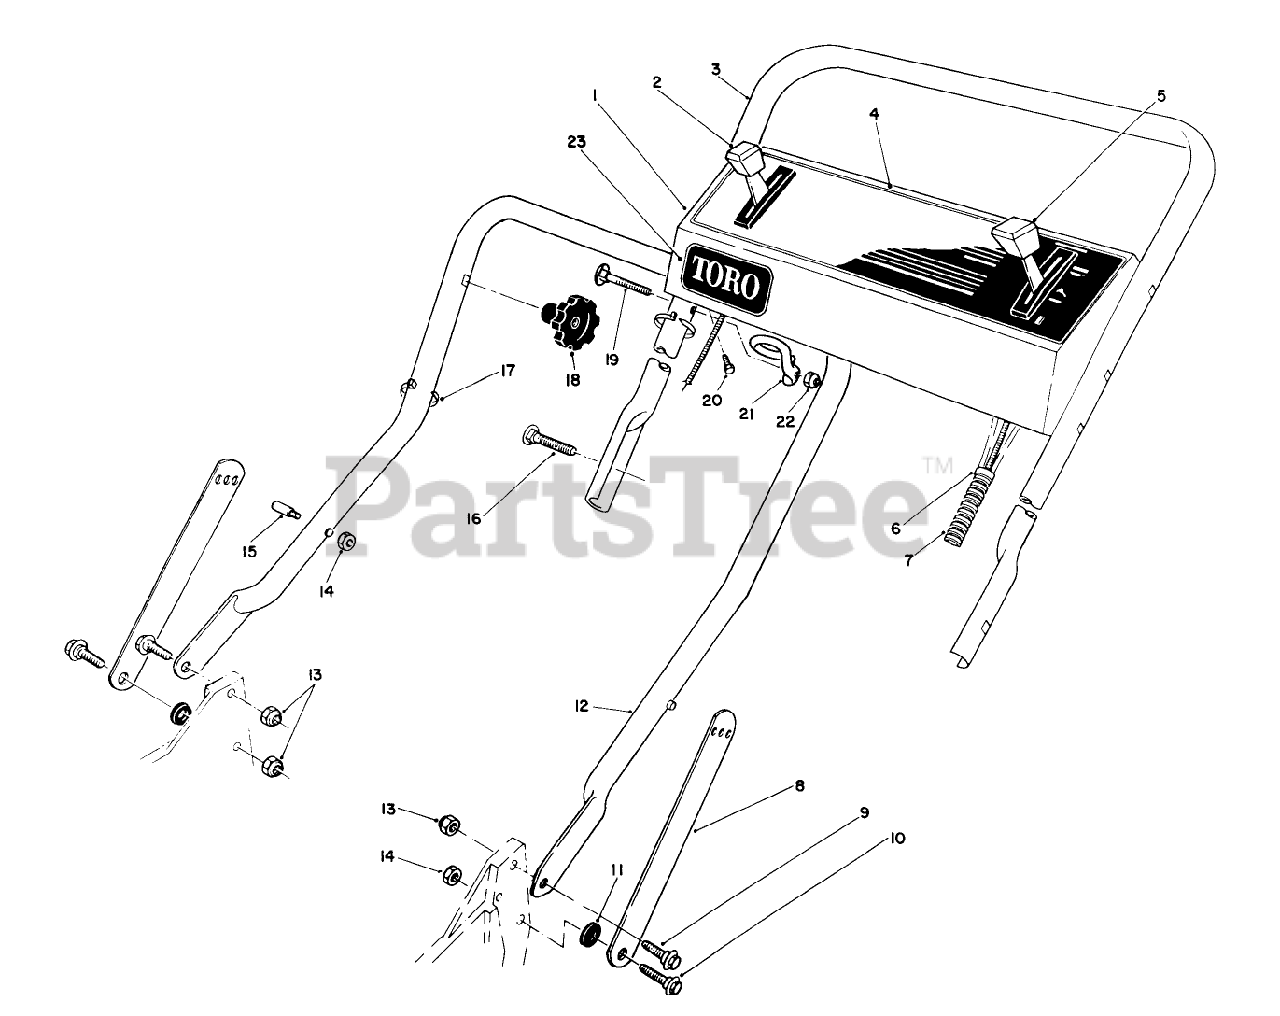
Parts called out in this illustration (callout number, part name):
6	FITTING-RING
9	SCREW-SHOULDER
10	SCREW-SHOULDER
11	SPACER
13	NUT-LOCK, NI
14	NUT-LOCK, NI
15	HANDLE PIN
17	TIE-CABLE
19	HANDLE SCREW
20	SCREW-HWHTF
22	NUT-LOCK, NI
23	DECAL
